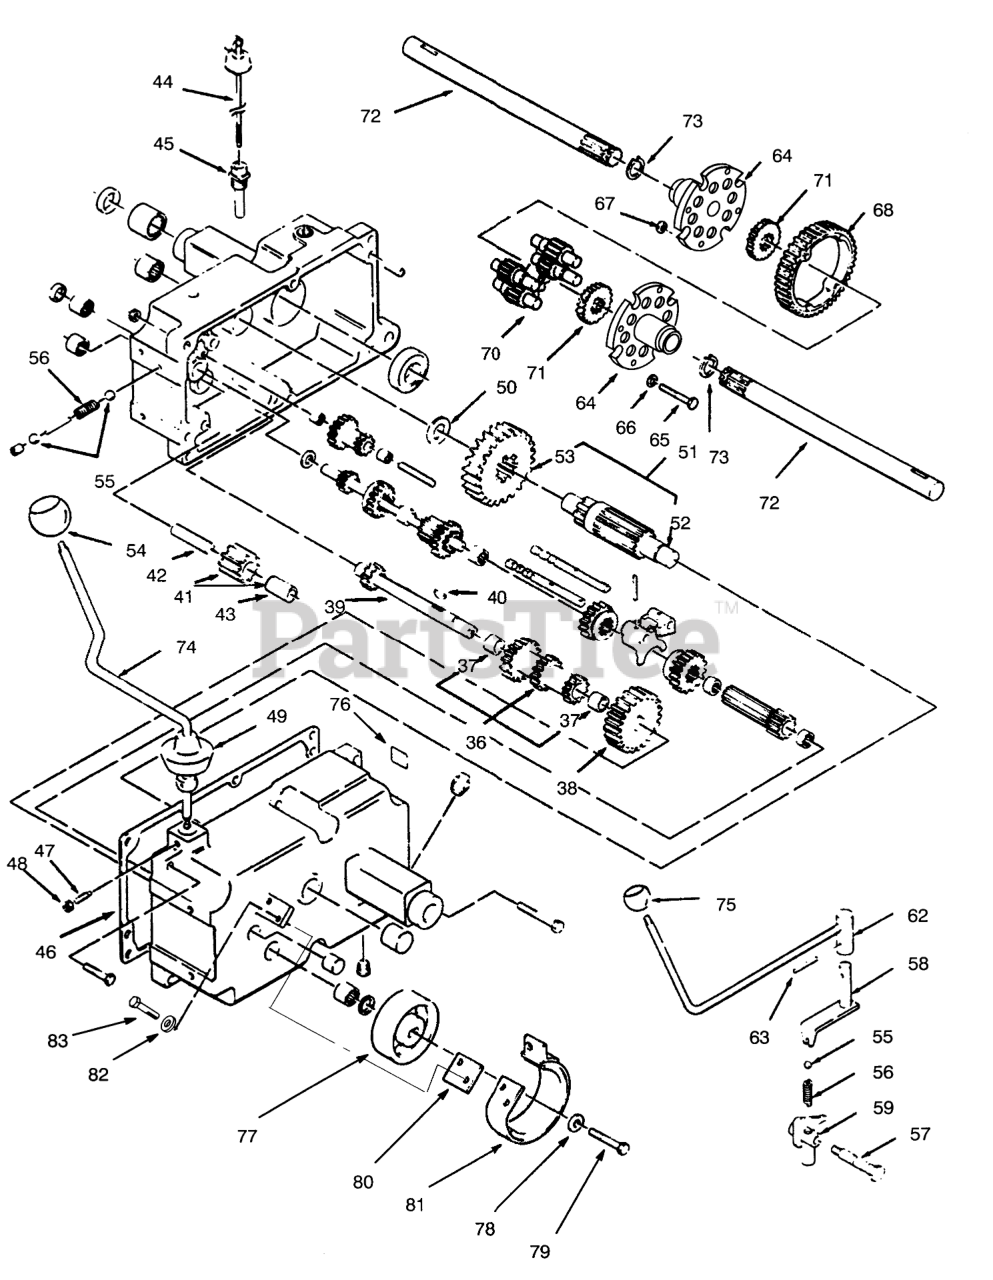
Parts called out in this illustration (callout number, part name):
36	Gear Assembly (Incl.Ref.#37)
37	BUSHING-BRONZE
38	GEAR-CLUSTER SHAFT
39	SHAFT-CLUSTER
40	KEY-WOODRUFF
41	Gear Assembly, Reverse Idler (Incl.Ref.#43)
42	PIN-DIFFERENTIAL
43	BUSHING
44	Dipstick
45	NIPPLE-FILL, TRANSMISSION
46	GASKET-TRANSMISSION
47	SETSCREW
48	NUT-HEX
49	COVER-DUST
50	WASHER-THRUST
51	Gear Assembly (Incl.Ref.#52&53)
52	PINION SHAFT
55	BALL-DETENT
56	SPRING-SHIFT STOP
57	BOLT-DETENT
58	SHIFT ASM
59	SHIFT FORK ASM
62	SHIFT ROD ASM
63	PIN-SPIROL
64	END CAP-DIFFERENTIAL
65	BOLT-HEX
66	WASHER
68	GEAR-DIFFERENTIAL RING, 43T
70	GEAR-PINION, 11T
71	GEAR-AXLE DIFFERENTIAL
72	AXLE-REAR
73	RING-SNAP
74	ASM-Rod
76	Decal-Unidrive
77	DRUM-BRAKE
78	WASHER
79	SCREW-HEX HD CAP
80	Plate-Stop
81	BRAKE BAND ASM
82	WASHER-LOCK
83	SCREW-HH
